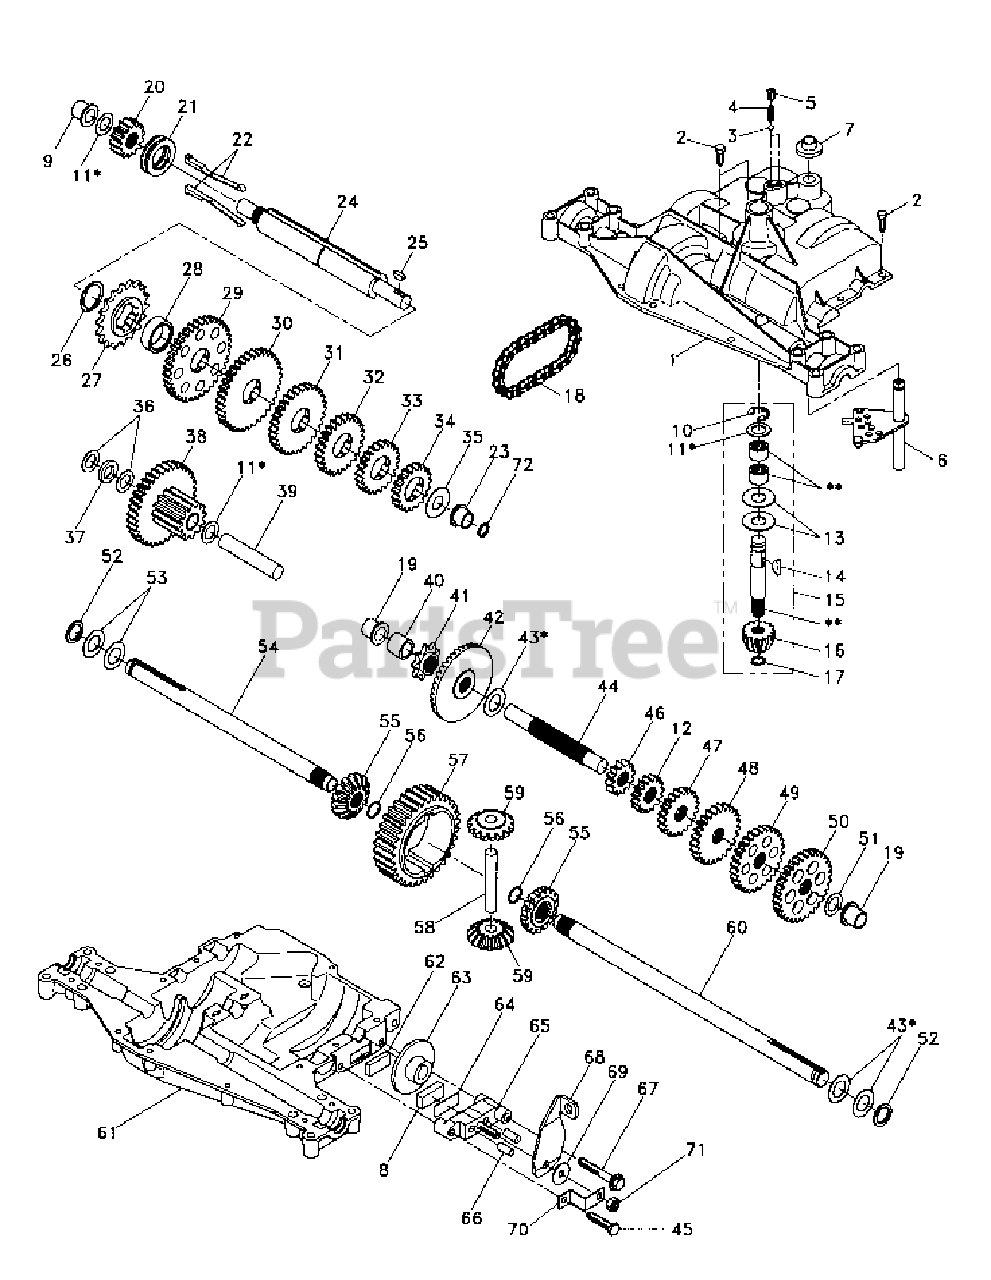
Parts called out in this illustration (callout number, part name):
1	Housing, Upper
2	Screw, Tapping, Large 1/4-20 x .734
3	Ball, Detent
4	Spring, Detent
5	Screw, Set
6	Kit, Shifter Assembly
7	Boot, Shifter
8	Puck, Friction
9	Bearing, Flange
10	Ring, Retaining
11	Assembly, Kit, Shim, .625 Shaft
12	Gear, Spur, 15 Teeth
13	Washer, Plain .632 x 1.38 x .046
14	Key, Woodruff, #9
15	Assembly, Kit, Input Shaft
16	Pinion, Bevel, 14 Teeth
17	Ring, Retaining
18	Chain, 24 Pitches
19	Bearing, Flange
20	Gear, Spur, 14 Teeth
21	Collar, Clutch
22	Assembly, Kit, Clutch Keys
23	Bearing, Flange
24	Shaft, Intermediate
25	Key, Woodruff, #61
26	Ring, Retaining
27	Sprocket, 18 Teeth
29	Gear, Spur, 37 Teeth
30	Gear, Spur, 35 Teeth
31	Gear, Spur, 30 Teeth
32	Gear, Spur, 25 Teeth
33	Gear, Spur, 22 Teeth
34	Gear, Spur, 19 Teeth
35	Washer, Plain .640 x 1.37 x .061
36	Washer, Plain .632 x 1.00 x .026
37	Spacer .630 x 1.00 x .169
38	Assembly, Gear, Combination, 12 Teeth and 35 Teeth
39	Shaft, Idler
40	Spacer .633 x .87 x .755
41	Sprocket, 9 Teeth
42	Gear, Bevel, 42 Teeth
43	Assembly, Kit, Shim, .750 Shaft
44	Shaft, Drive
45	Screw, Tapping, Large 5/16-18 x 1.44
46	Gear, Spur, 12 Teeth
47	Gear, Spur, 20 Teeth
48	Gear, Spur, 25 Teeth
49	Gear, Spur, 28 Teeth
50	Gear, Spur, 31 Teeth
51	Washer, Plain .632 x 1.00 x .060
52	Washer, Neoprene
53	Washer, Plain .758 x 1.25 x .031
54	Axle, L.H.
55	Gear, Miter, 15 Teeth
56	Ring, Retaining
57	Gear, Spur, 32 Teeth
58	Shaft, Cross
59	Gear, Miter, 15 Teeth
60	Axle, R.H.
61	Housing, Lower
62	Puck, Friction
63	Disc, Brake
65	Jaw, Brake
66	Pin, Dowel
67	Screw, Tapping 5/16-18 x 2.25
68	Lever, Actuating
69	Washer, Plain .321 x 1.00 x .055
70	Bracket, Anti-Rotation
71	Locknut 5/16-24
73	Grease
